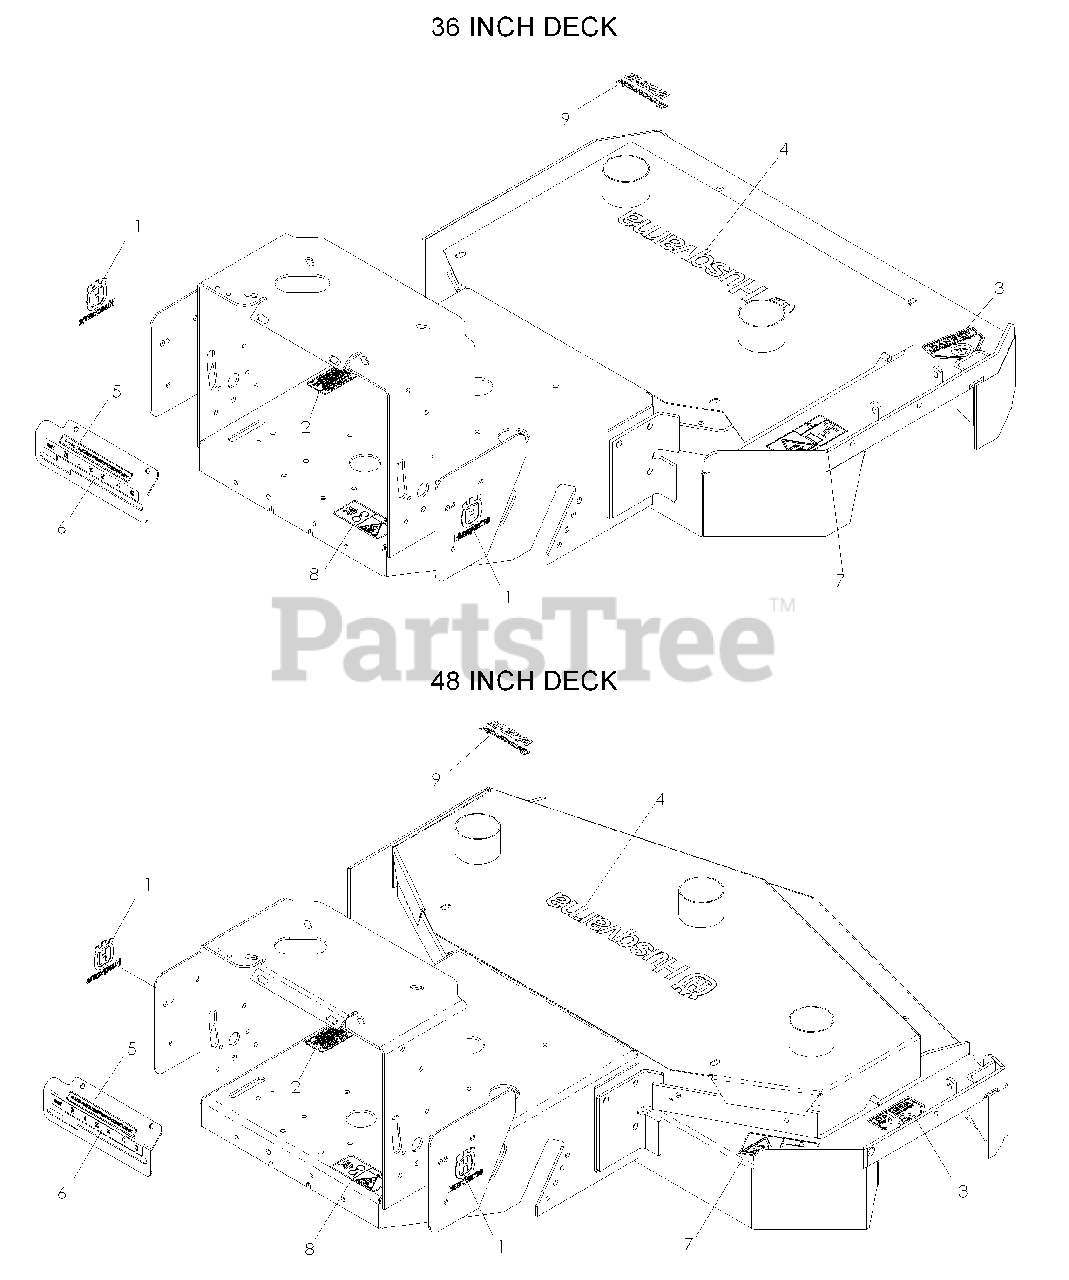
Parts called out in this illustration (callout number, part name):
1	DECAL, CROWN
2	DECAL, PROP 65
3	DECAL, CPSC
4	DECAL, HUSQVARNA
5	DECAL, CLUTCH
6	DECAL, SHIFT
7	DECAL, SEVERING
8	DECAL, BELT DRIVE
9	DECAL, W3613
9	DECAL, W4815
